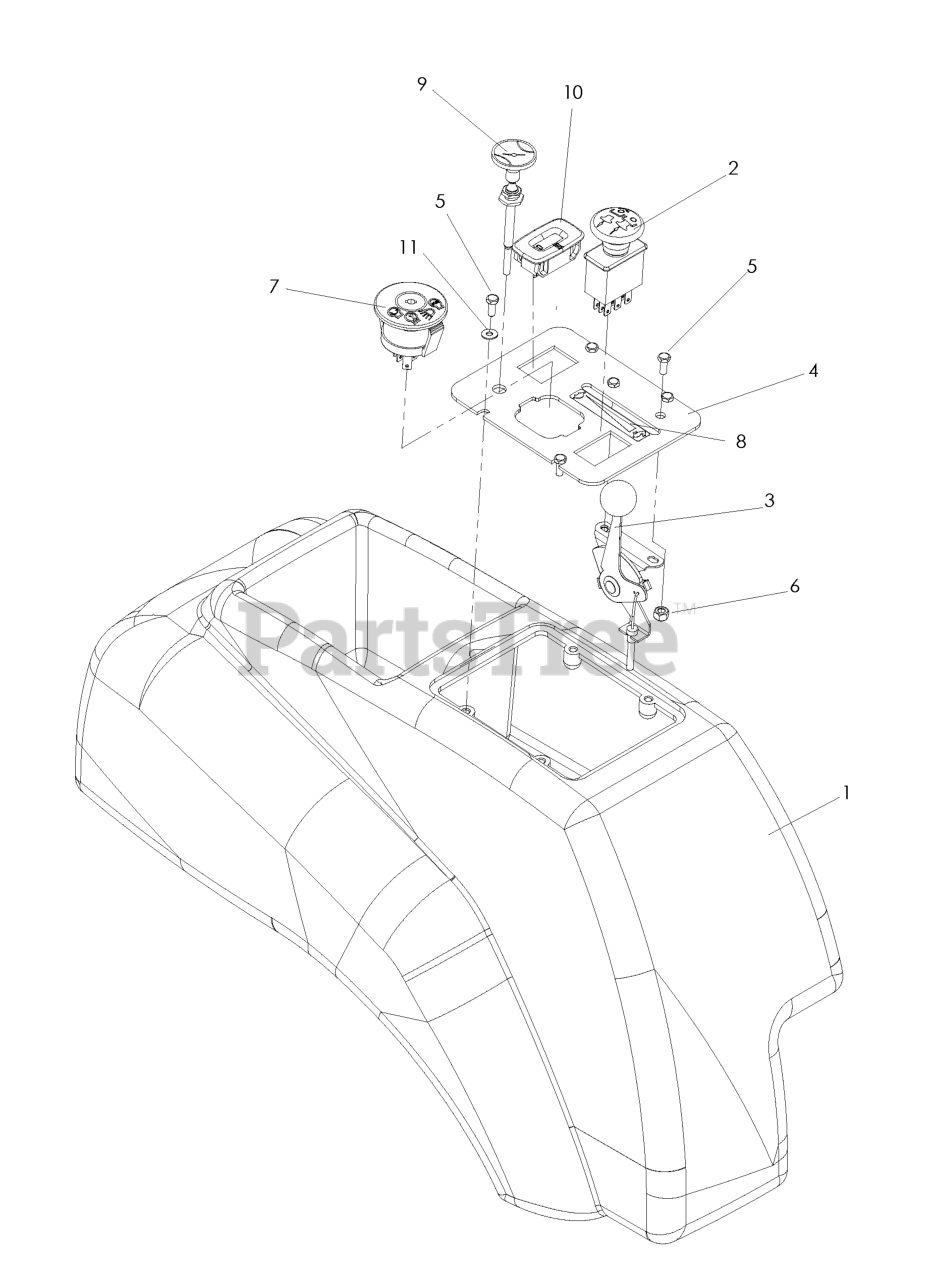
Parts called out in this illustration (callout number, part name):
1	FENDER CONSOLE
2	RP.SWITCH, BLADE
3	THROTTLE CABLE
4	CONSOLE PLATE, BLACK
5	HCS #10-24 X 1/2
6	NUT 10-24 NYLOC
7	RP IGNITION SWITCH
8	DECAL, THROTTLE
9	CHOKE CONTROL
10	HOUR METER
11	WASHER #10
